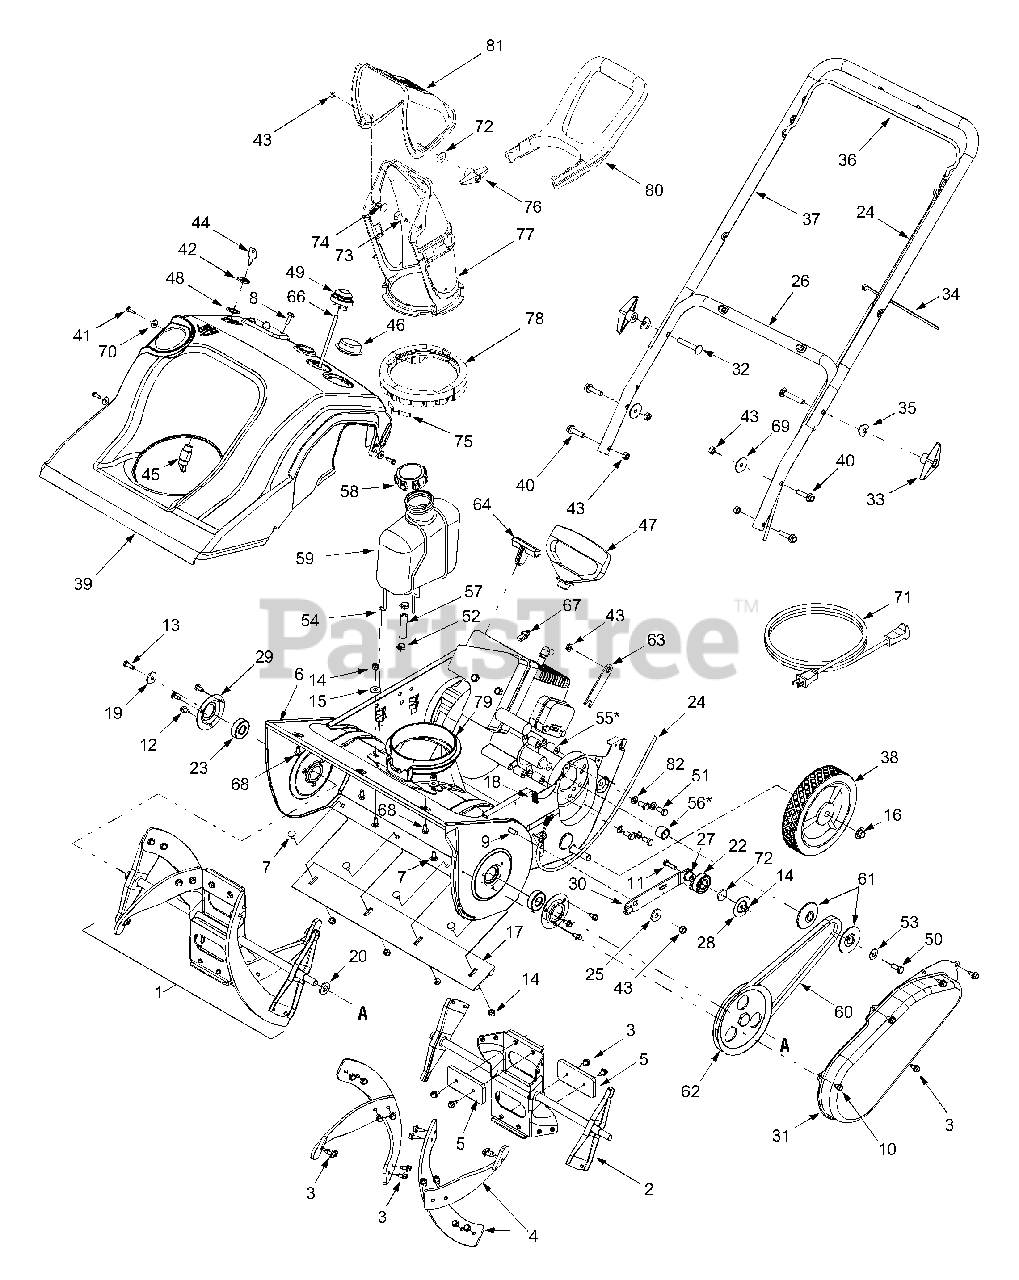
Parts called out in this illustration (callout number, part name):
1	Auger Ass'y 21" complete w/Solid Shaft
3	Hex B-Tap Scr. 1/4-28 x .625
4	Rubber Spiral-Crescent
5	Rubber Paddle
8	Hex Wash B-Tapp Scr #10-16 x .625" Lg.
9	Hex Hd Cap Scr 5/16-18 x .75
10	Self Tapping Scr. 1/4-20 x .375" Lg
11	Hex Screw 1/4-20 x 1.00 Gr. 5
12	Hex Tap Scr. 1/4-14 x .50" LG.
13	Hex Hd Cap Scr 5/16-18 x .75
14	Flanged Lock Nut 1/4-20 Gr. F Nylon
15	Flat Washer .265 ID x .938 OD x .120
16	Push Cap x 1/2" Rod
17	Shave Plate 2.66 x 19.88 Double
18	Extension Spring .33 OD x 1.12 Lg.
19	Flat Washer .265 ID x .938 OD x .120
20	Flat Washer .510 ID x 1.00 OD x .125
22	Ball Bearing .787 ID x 1.85 OD x .56
23	Ball Bearing 17 x 40 x 12
24	Clutch Cable
25	Shoulder Spacer .25 THK
27	Flange Spacer
28	Belt Keeper
32	Carriage Bolt 5/16-18 x 2.0 Gr. 1
33	Handle Knob Assembly 5/16-18
34	Cable Tie
35	Saddle Washer .320 ID x .93 OD
38	Wheel-3 Spoke, 7 x 1.61
39	Shroud Ass'y
40	Hex Flg. Scr 5/16-18 x 1.50" Gr. 5
41	Hex B-Tapp Wash Scr #10-16 x .625
42	Hex Nut 5/8-32 x .12 Special
43	Hex Flanged Lock Nut 5/16-18 Gr. 5
44	Ignition Key
45	Key Switch-Electric Start
46	Plastic Cap 1.75 Dia x .72
47	Recoil Handle
48	L-Washer Internal .625 ID x 1.058 OD
49	Primer But ton
50	Hex Screw 5/16-24 x .75 Gr. 5
51	Hex Screw 5/16-18 x 1.5 Gr. 5
52	Hose Clamp
53	Cupped Washer .340 ID x .872 OD x .060
54	Gas Tank Wire Support
55	Spacer, .325 ID x .625 OD x .88
56	Spacer, .630 ID x .88 OD x .680
57	Fuel Line 17" Lg.
58	Fuel Cap
59	Fuel Tank 2 Quart
60	V-Belt 3/8 x 34.4" Lg.
61	Pulley Half, .625 ID x 2.25 OD
62	Pulley, 3/8 x 1/2-20 x 6.0
65	Hex Flange L-Nut 5/16-18 Gr. 5
66	Primer Tube
67	Choke Lever Knob
68	Hex Screw 1/4-15 x .50
69	Flat Washer .320 ID x 1.25 OD
70	Flat Washer .194" ID x .62" OD x .063
71	Cord-Extension 110V 3M -2 Prong
72	Flat Washer .349 ID x .879 OD x .063
73	Carriage Bolt 5/16-18 x 1.0 (Custom)
74	Carriage Bolt 5/16-18 x .75 Gr. 1
75	Chute Adjustment Spring
76	Handle Knob Ass'y
77	Lower Chute 5" Dia.
78	Ring-Lower Chute
79	Chute Adapter 5" Dia.
80	Handle-Chute 5" Dia.
81	Upper Chute w/export label
82	L-Wash 5/16 ID
